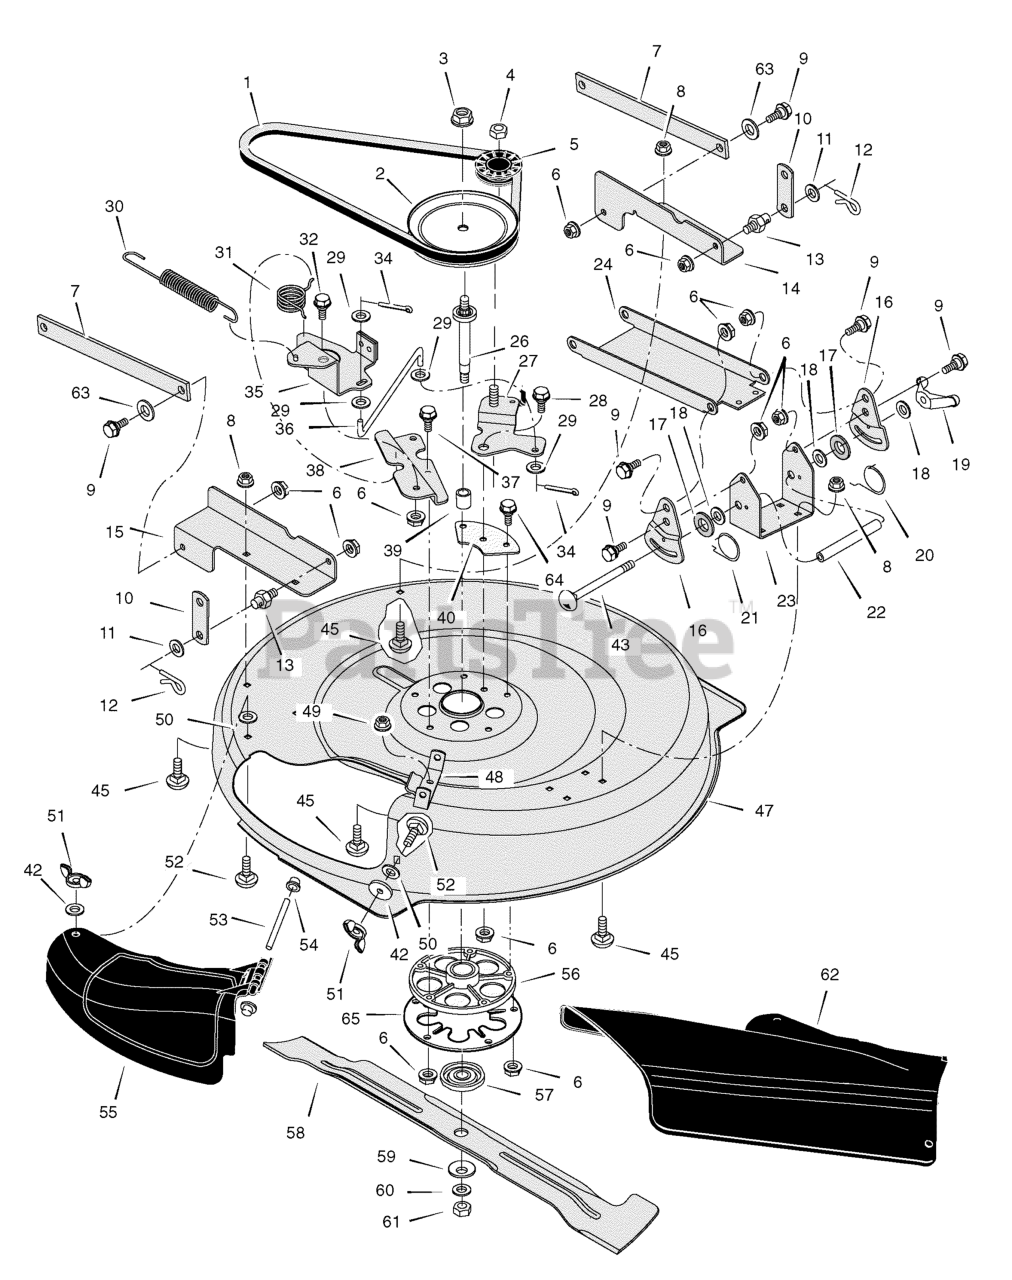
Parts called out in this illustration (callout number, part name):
1	Belt, Blade Drive
2	Pulley, Input
3	Locknut
4	Nut, Flange
5	Pulley, Idler
6	Nut, Flange
7	Arm, Rear
8	Nut, Flange
9	Bolt, Shoulder
10	Link, Lift
11	Washer
12	Pin, Hair
13	Pin, Threaded Shoulder
14	Bracket, Left Rear
15	Bracket, Right Rear
16	Plate, Adjustment
17	Pad, Friction
18	Washer
19	Wingnut
20	Spring, Left Torsion
21	Spring, Right Torsion
22	Tube, Spacer
23	Bracket, Deck
24	Hanger, Front
26	Shaft, Splined
27	Arm Assembly , Idler
28	Bolt, Shoulder
29	Washer
30	Spring, Extension
31	Spring, Torsion
32	Bolt, Shoulder
34	Pin, Cotter
35	Arm Assembly, Brake
36	Link, Idler Arm
37	Bolt
38	Bracket, Brake Mounting
39	Spacer, Jackshaft
40	Plate, Idler Mounting
42	Washer
43	Bolt, Carriage
45	Bolt, Carriage
47	Housing, Blade
48	Hinge, Mulching Cover
49	Nut, Flange
50	Nut, Speed
51	Wingnut
52	Bolt, Carriage
53	Rod, Chute Deflector
54	Cap, Push
55	Cover, Mulch
56	Mandrel Housing
57	Adapter, Blade
59	Washer, Cup
60	Washer
61	Nut, Blade Mount
62	Deflector, Chute
63	Bolt, Carriage
65	Plate, Jackshaft Support
